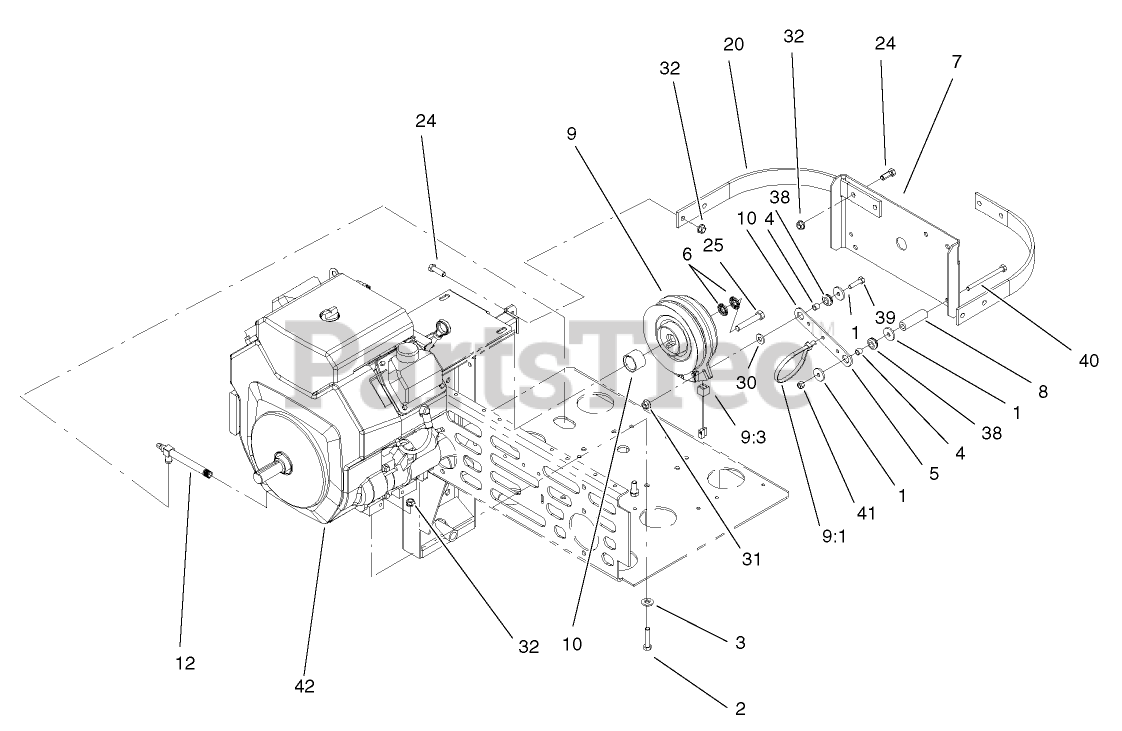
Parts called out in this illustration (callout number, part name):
1	WASHER
2	SCREW-HH
3	WASHER-BELLEVILLE
4	SPACER
5	STRAP-CLUTCH, BRAKE
6	WASHER-SPRING
7	GUARD-CLUTCH
8	SPACER-ANCHOR, CLUTCH
9	CLUTCH ASM
9:1	TIE-PLASTIC
9:3	HARNESS-JUMPER, CLUTCH
10	SPACER-CLUTCH
12	VALVE-OIL DRAIN, LONG
20	BRACKET-GUARD, TOP
24	SCREW-HH
25	SCREW-HH
30	WASHER-FLAT
31	NUT-HF
32	NUT-HHF, WHIZ
38	GROMMET
39	SCREW-HH
40	SCREW-HH
41	NUT-LOCK, NI
